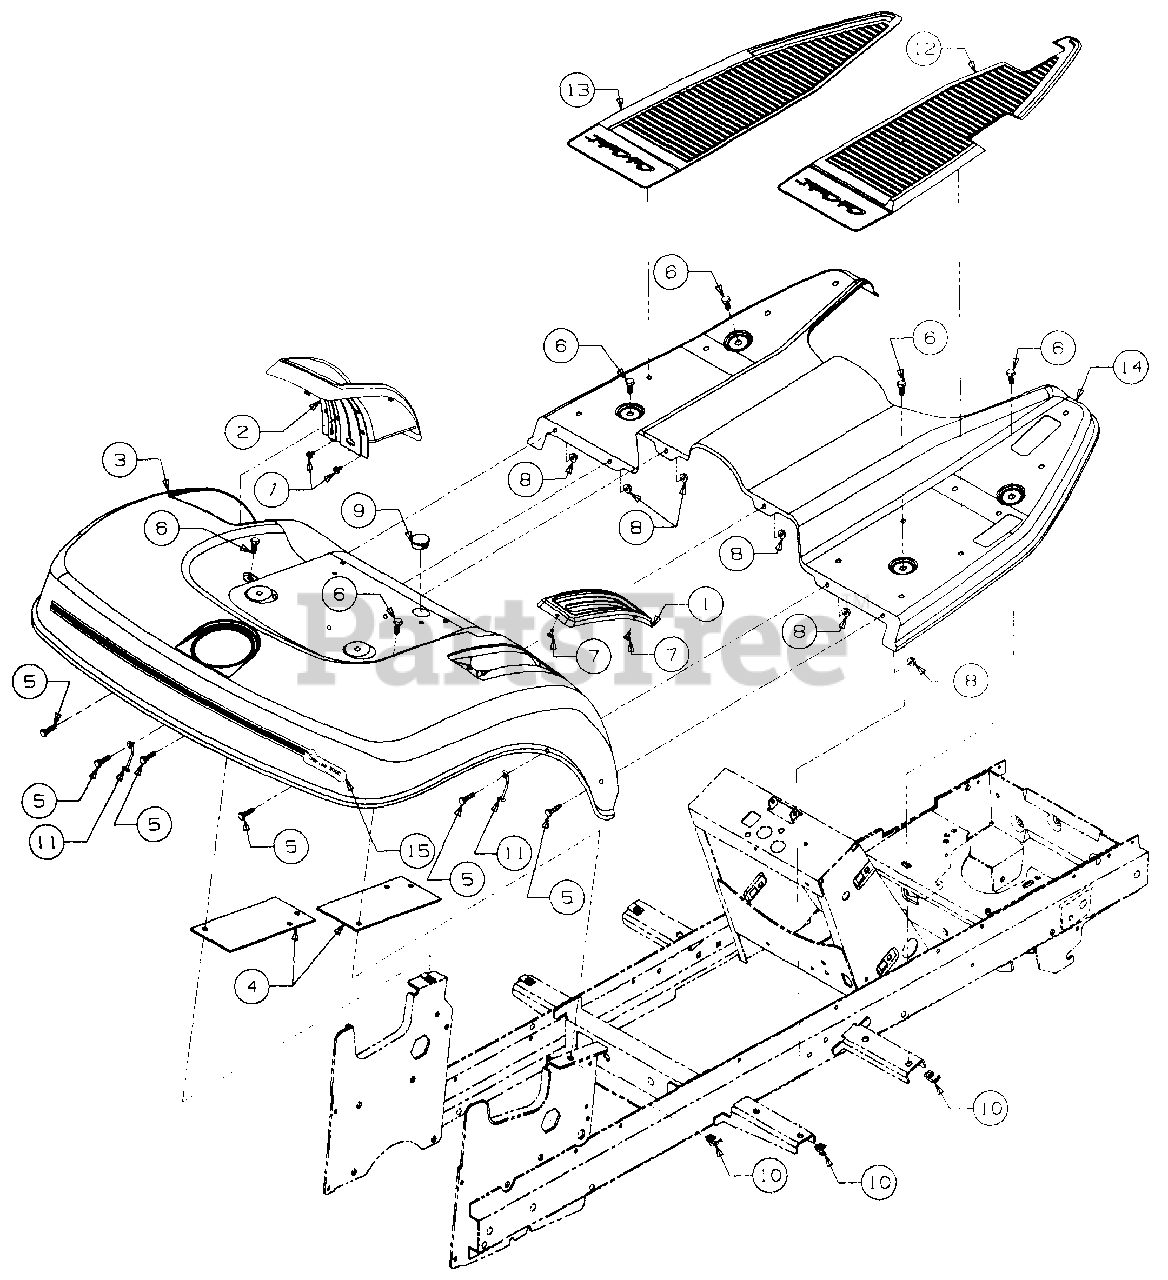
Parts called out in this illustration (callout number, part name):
1	Cover, Hydro Shifter
2	Cover, Implement Lift
6	Screw, Hex Wash Sf-Tapp 5/16-18 x .75 Lg
7	Screw, Hex Tapp, #10 x .38 Lg
8	Nut, Hex Flange Lock, 1/4-20
9	Bushing, Snap, 7/8 ID
10	U-Nut, 5/16-18
11	Retainer, Hook
12	Pad, RH Foot
13	Pad, LH Foot
14	Running Board w/Graphic Warning
15	Graphic, Rear Fender
